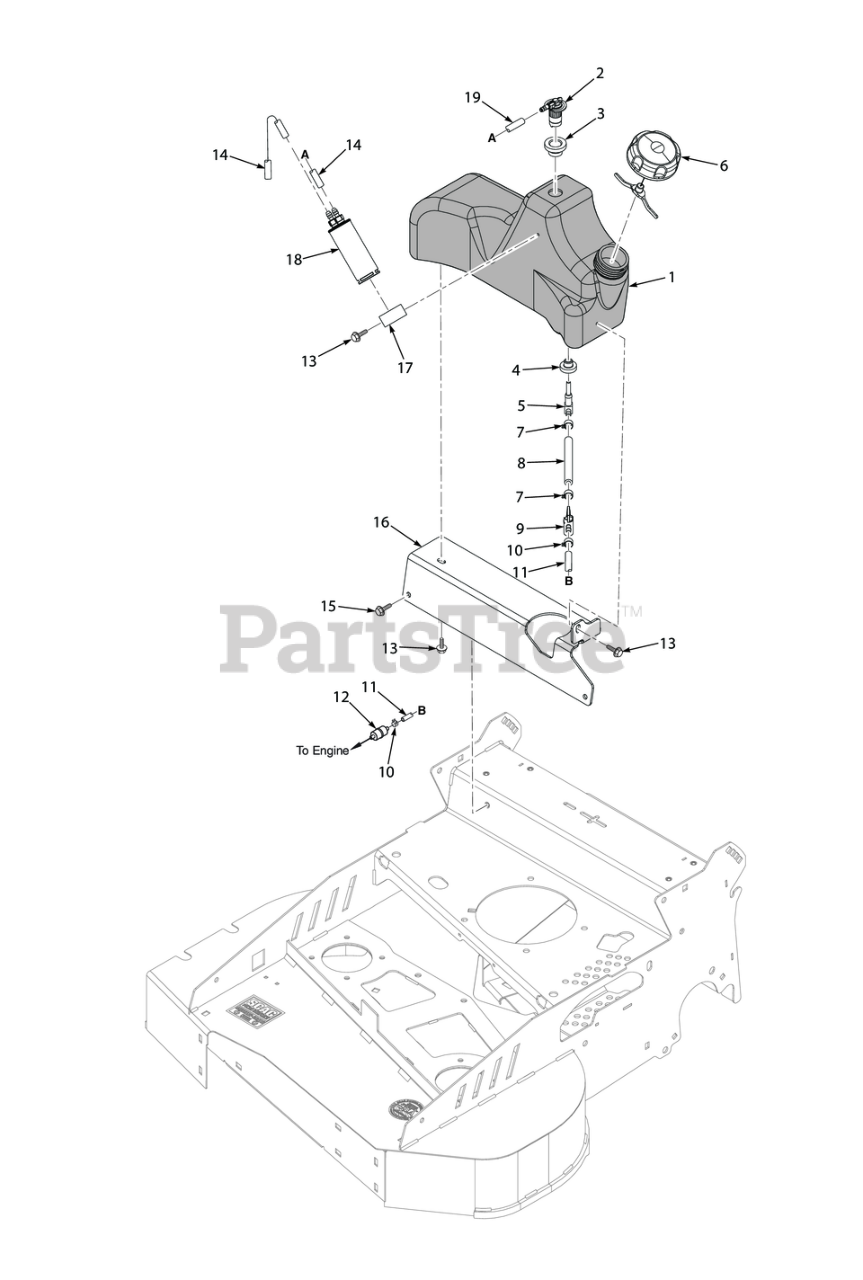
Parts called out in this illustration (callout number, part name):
1	Fuel Tank Assembly w/Decal (incl. #2, #3, #4, #5)
2	Valve
3	Grommet, Valve
4	Bushing, 0.56" Dia. Viton
5	Elbow, 90 Degree w/Screen
6	Cap, Fuel Tank
7	Clamp, Fuel Hose 1/4" Hose I.D.
8	Fuel Hose, 1/4" I.D. Non-Perm (791DFI Fuel Return) - Order by Inch
9	Valve, Fuel Shutoff
10	Clamp
11	Fuel Hose
12	Fuel Filter
13	CAP SCREW, 1/4-20 X 1/2" SERRATED FLANGE HEX
14	Hose, Vapor Recovery 3/16" (order by inch)
15	CAP SCREW, 1/4-20 X 1/2" SERRATED FLANGE HEX
16	Bracket, Fuel Tank
17	Clamp, 1-1/2" Cable
18	Canister, Carbon 1.28 Gal.
